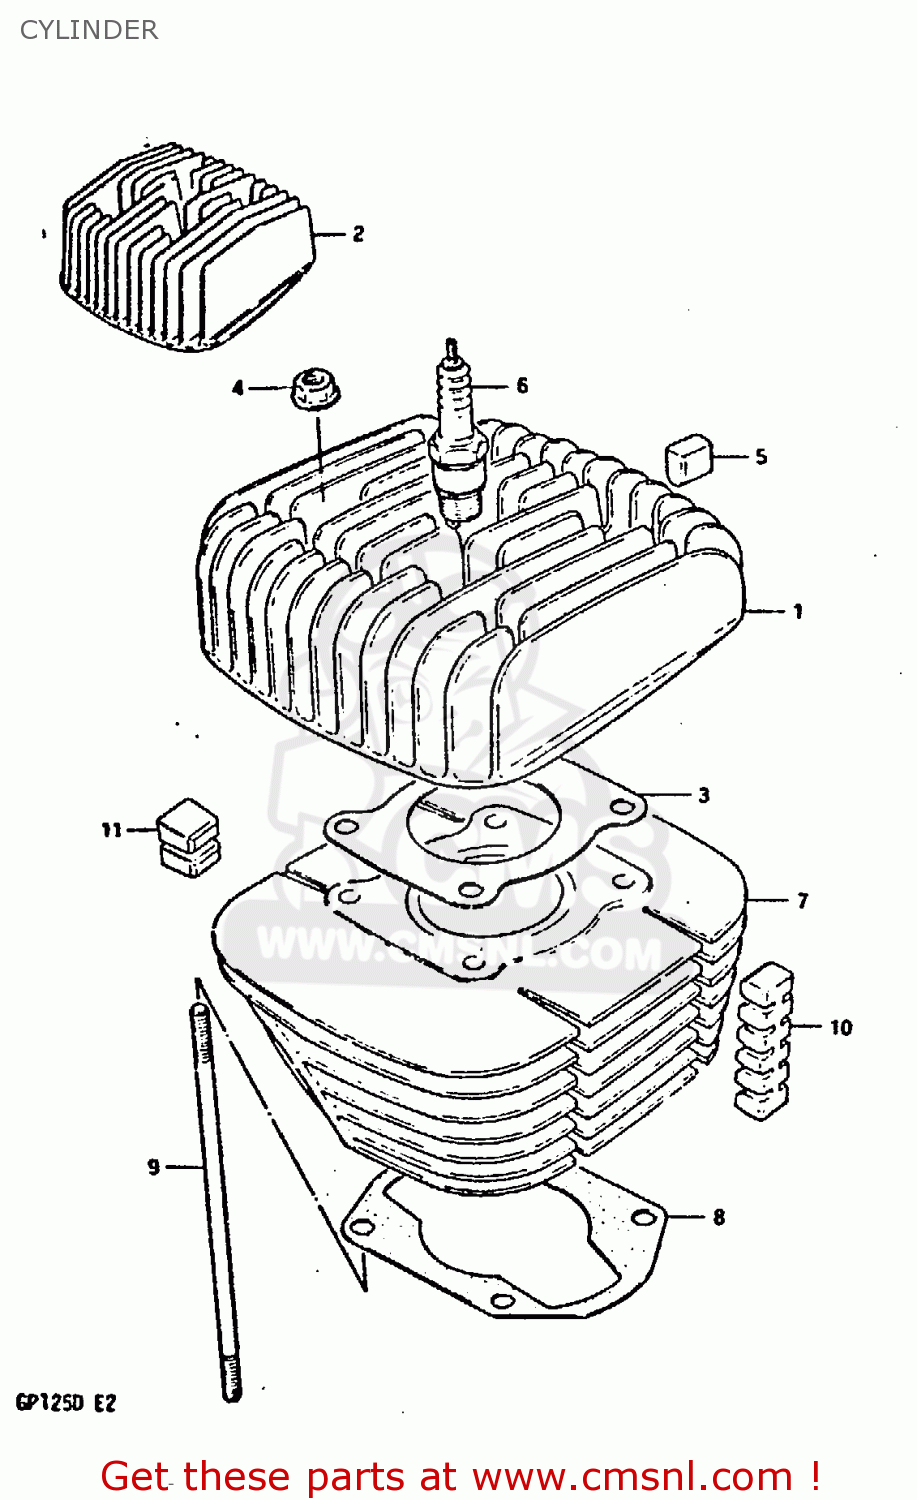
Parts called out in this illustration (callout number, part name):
1	CYLINDER HEAD
3	GASKET (MCA)
4	NUT
5	PAD,CYLINDER
6	PLUG,SPARK(B8HS)
7	CYLINDER
8	GASKET, CYLINDER (MCA)
9	BOLT,STUD
10	RUBBER PAD, CYLINDER (1)
11	PAD,CYLINDER
